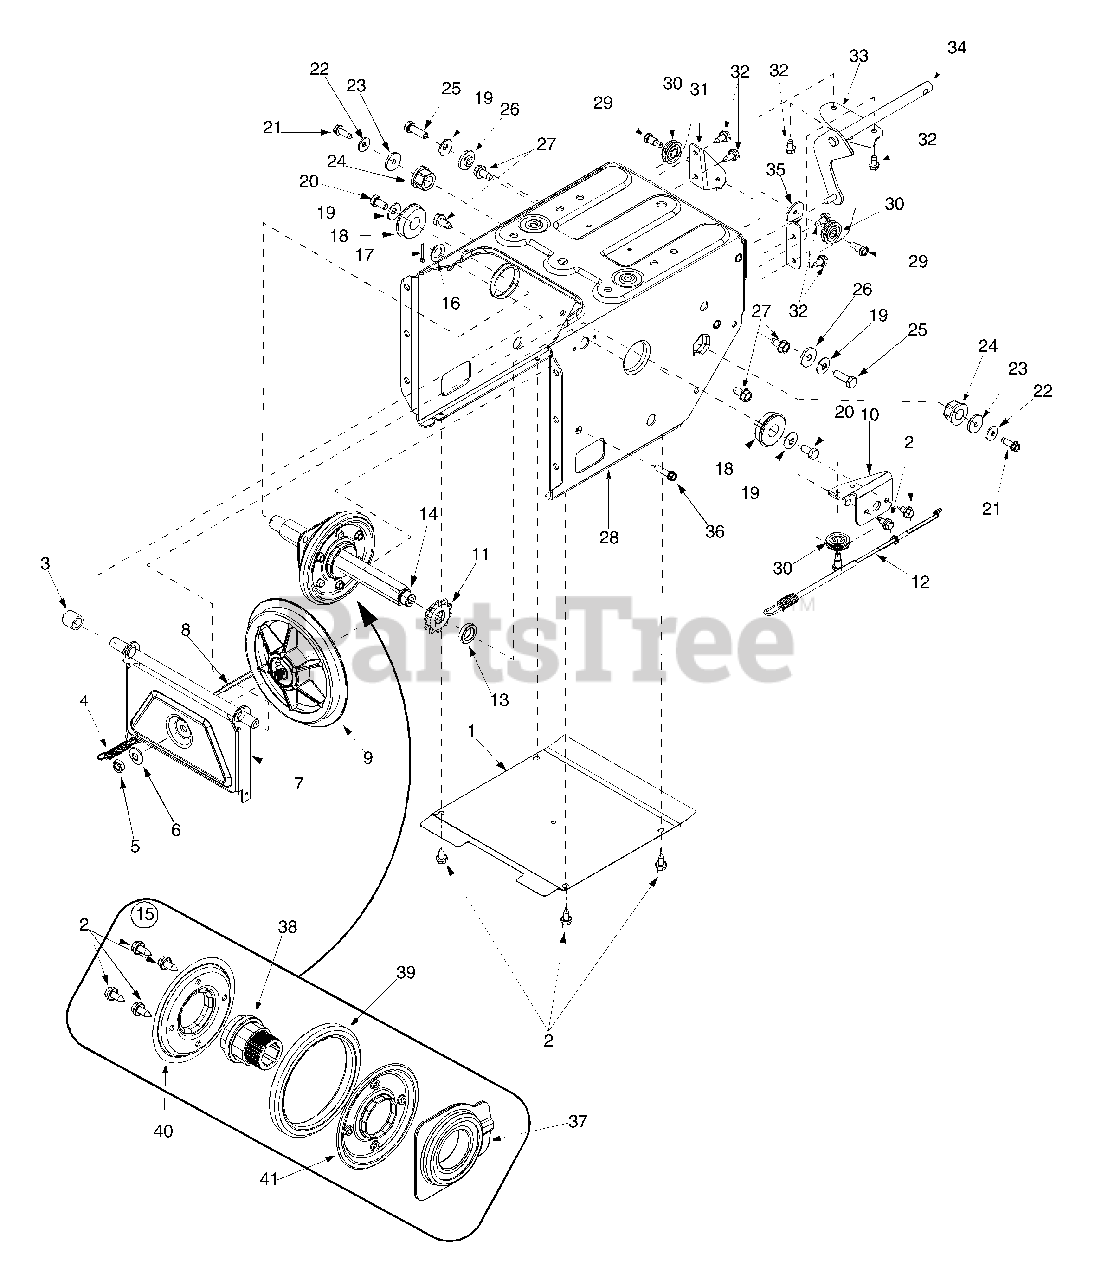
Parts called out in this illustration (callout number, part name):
3	Spacer.508 ID x.75 OD
4	Extension Spring
5	Jam Nut 3/8-24
6	Bell Washer.401 ID x.87 OD
9	Friction Disc
12	Auger Cable 44.75"
13	Spacer.675 ID x 1" OD
14	Hex Track Shaft
15	Friction Wheel Assembly
16	Flat Washer.536 ID x.93 OD
17	Cotter Pin
18	Ball Bearing
19	Bell Washer.34 ID x.872 OD
20	Hex Cap Screw 5/16-18 x.625
21	Tap Screw 1/4-20 x.75
22	Bell Washer.265 ID x.75 OD
23	Flat Washer 1/4 ID x.93 OD
24	Hex Flange Bearing
25	Hex Cap Screw 5/16-18 x 1"
26	Shoulder Spacer
27	Tap Screw 5/16-12 x.750
29	Hex Screw 1/4-28 x.375
30	Cable Roller
37	Friction Wheel Bearing
38	Friction Wheel Hub
39	Friction Wheel Rubber
40	Friction Plate
41	Friction Plate
